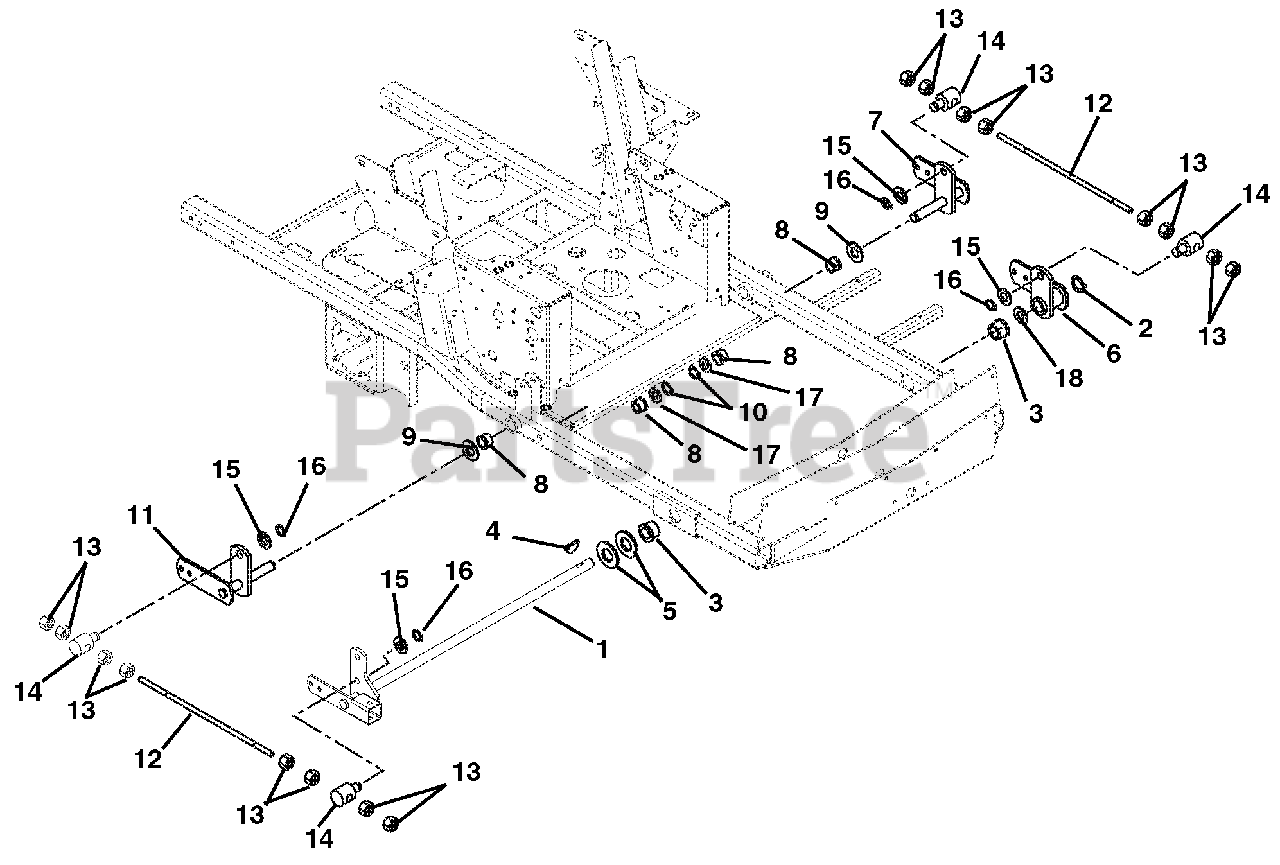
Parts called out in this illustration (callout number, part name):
1	Lift, Mower
2	Ring, Retaining External 1.00 x .078
3	Bushing, Flange Nylon 1.020 x 1.385 x .75 x 1.75
4	Key, Woodruff .25 x 1.00
5	Washer, Flat Steel 1.063 x 2.00 x .134
6	Weldment, Lift Arm Front
7	Weldment, Lift Arm Shaft Left Hand
8	Bushing, Flange Nylon .762 x 1.00 x .58 x 1.48
9	Washer, Hardened Steel .758 x 1.23 x .031
10	Ring, Retaining External .689 x .077
11	Weldment, Lift Arm Shaft Right Hand
12	Rod, Lift Assist
13	Nut, Jam .50-13
14	Pivot, Mower Lift
15	Washer, Flat Steel .63 x 1.005 x .062
16	Ring, Retaining External .625 x .05
17	Washer, Flat Steel .755 x 1.25 x .125
18	Washer, Hardened Thrust 1.00 x 1.55 x .03
